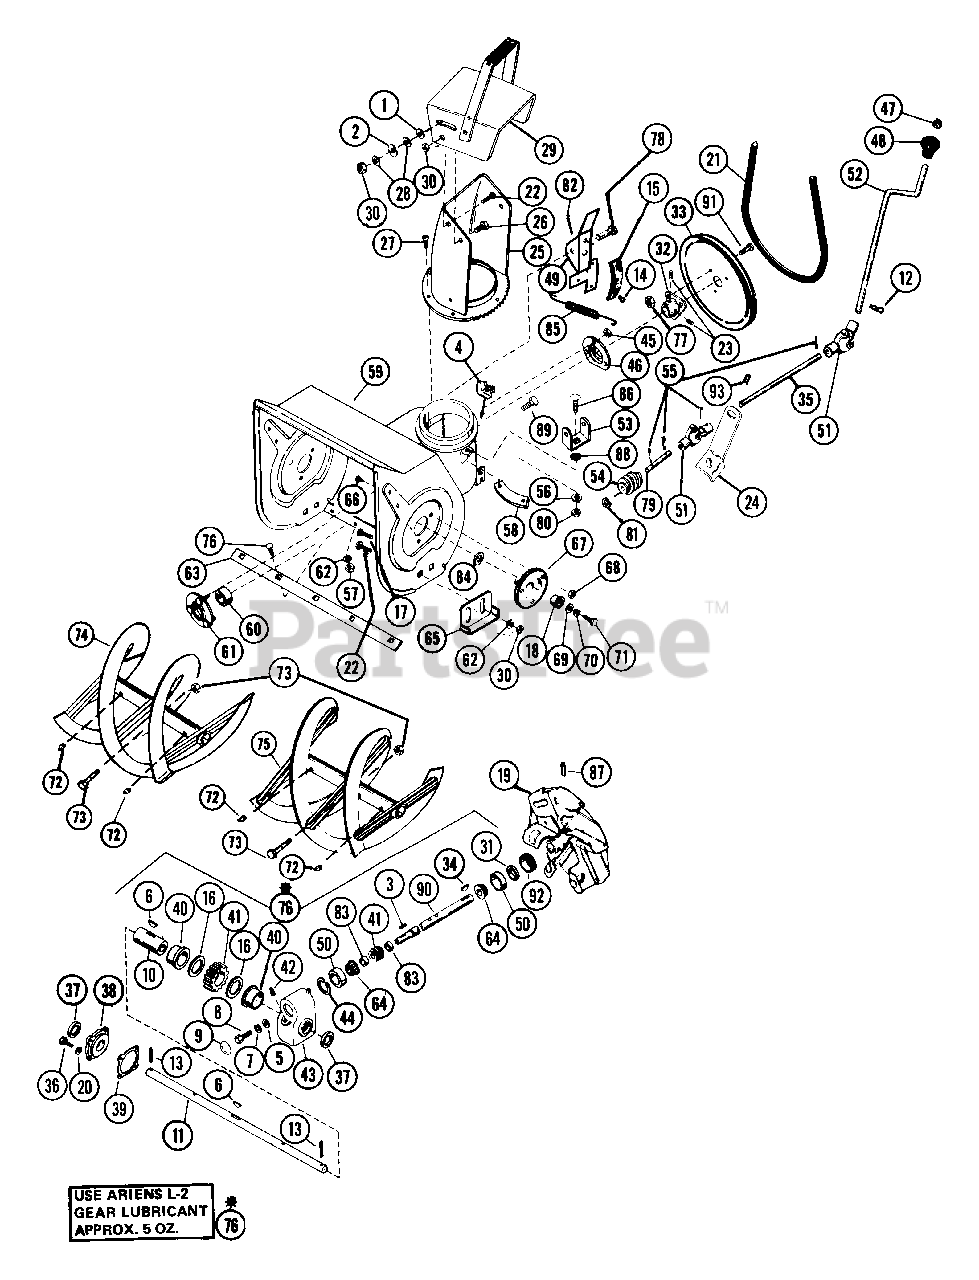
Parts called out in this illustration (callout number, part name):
1	WSHR-PLASTIC .390X.875X.062
2	WAVE WASHER .390X.655X.110
3	KEY-SQ .188X1.0X.188 SAE 8630
4	NUT-RETNR .38-16 TINRMAN
5	WSHR-FL-STL .328X1.0X.094
6	KEY-WDRF .25X.875X.375 SAE A
7	WSHR-LK .312X.097 PL HVY
8	BLT-HEX .31-18X.75 PL GR2
9	DUST CAP
10	GEAR CASE SHAFT
11	SHAFT, 32" RAKE - 1.00 DIA.
12	PIN-HAIR INT .08X.38X1.42 YWZC
13	PIN-ROLL .188X1.50
14	RVT-TBLR .187X.375 OH ST PL
15	BRAKE LINING
16	WSHR-FL-STL 1.625X2.500X.012
17	BLT-RDHDSQSHNK .38-16X1.00 PL
18	BSHG-FLG 1.000X1.12X.62X1.50BR
19	FAN - 14"
20	WSHR-LK-EXT. 250 ID
21	V-BELT, 4L-RAW EDGE
22	BLT-RDHDSQNK .38-16X.75 SHT PL
23	SCR-SET .32-18X.38 SKHCUPNL OH
24	CHUTE CRANK BRACKET
25	DISCHARGE CHUTE
26	BLT-HEX .38-16X.75 PL GR2
27	SCR-TAP 10-24X.375 HWH PL TR
28	WSHR-FL-STL.406X.812X.065PL
29	DEFLECTOR W/ DECAL
30	NUT-LK-CTR .375-16 GR A PL
31	SEAL 1.000X1.312X.150
33	PLY-V 9.0 X 1.25 3BLT
34	KEY-WDRF .188X.875X.375 SAE11
36	BLT-HEX .25-20X.75 PL GR2
37	SEAL 1.625X2.125X.250
38	GEAR CASE COVER
40	BSHG-FLG .683X1.87X1.68X2.250
41	WORM & GEAR SERVICE ASSEMBLY
42	PIPE PLUG
43	GEAR CASE - CAST IRON
44	RG-RTNG-INT 1.781X.062
45	NUT-LK-CTR .250-20 PL
46	BEARING FLANGE
47	CAP, 3/8 ROD YWZC
49	BRAKE ARM ASSEMBLY
50	BRG-CUP 1.781X.475
51	UNIVERSAL JOINT ASSY
52	CHUTE CONTROL CRANK
53	WORM CLEVIS
54	WORM GEAR L. H.
55	PIN-ROLL .125X.75
56	WSHR-LK .313X.062
57	NUT-LK .312-18 GR A PL
58	CHUTE CLAMP
59	BLOWER HOUSING W/DECALS 32
60	BRG-BALL 1.0X2.0X.56
61	BEARING FLANGE
62	WSHR-FL-STL .38X.875X.083 PL
63	SCRAPER BLADE 32"
64	BRG-CONE .750X.61
65	SKID SHOE
66	BLT-SERNK SL .25-20X.50 PL
67	BEARING SUPPORT
68	NUT-LK-FLG .250-20 PL
69	WSHR-FL-STL .511X1.441X.125 PL
70	WSHR-LK .500X.151 HVY PL
71	BLT-HEX .50-13X1.00 PL GR2
72	SPIN DRIVE ZERK FITTING
73	SHEAR BOLT SERVICE ASSEMBLY
74	RAKE, RIGHT-32"(1ID X 15.75OD)
75	RAKE, LEFT-32"(1"ID X 15.75OD)
76	GEAR CASE - CAST IRON
77	NUT-FLG. .312-18 PL
78	CLEVIS PIN
79	WORM SHAFT
80	NUT-HEX .312-18
81	WAVE WASHER .406X.750X.063FH
82	PIN-HAIR INT .06X.18X.77
83	BSHG, SPCR .755X1.12X.50 PM
84	WSHR-FL-STL 1.010X1.505X.062PL
85	SG-TENS .062X.56X8.0 WLD 11
86	BLT-RDHDSQNK .31-18X.75 GR5 PL
87	PIN-ROLL .313X1.75
88	WSHR-LK-EXT .375X.035 PL
89	BLT-SCRHFWH .38-16X.75 PL
90	SHAFT, WORM - 1.00 DIA.
91	BLT-SERRDHD SL .31-18X.87 PL
92	ADJUSTMENT PLUG - 1" SHAFT
93	PIN-HAIR INT .08X.38X1.42 YWZC
